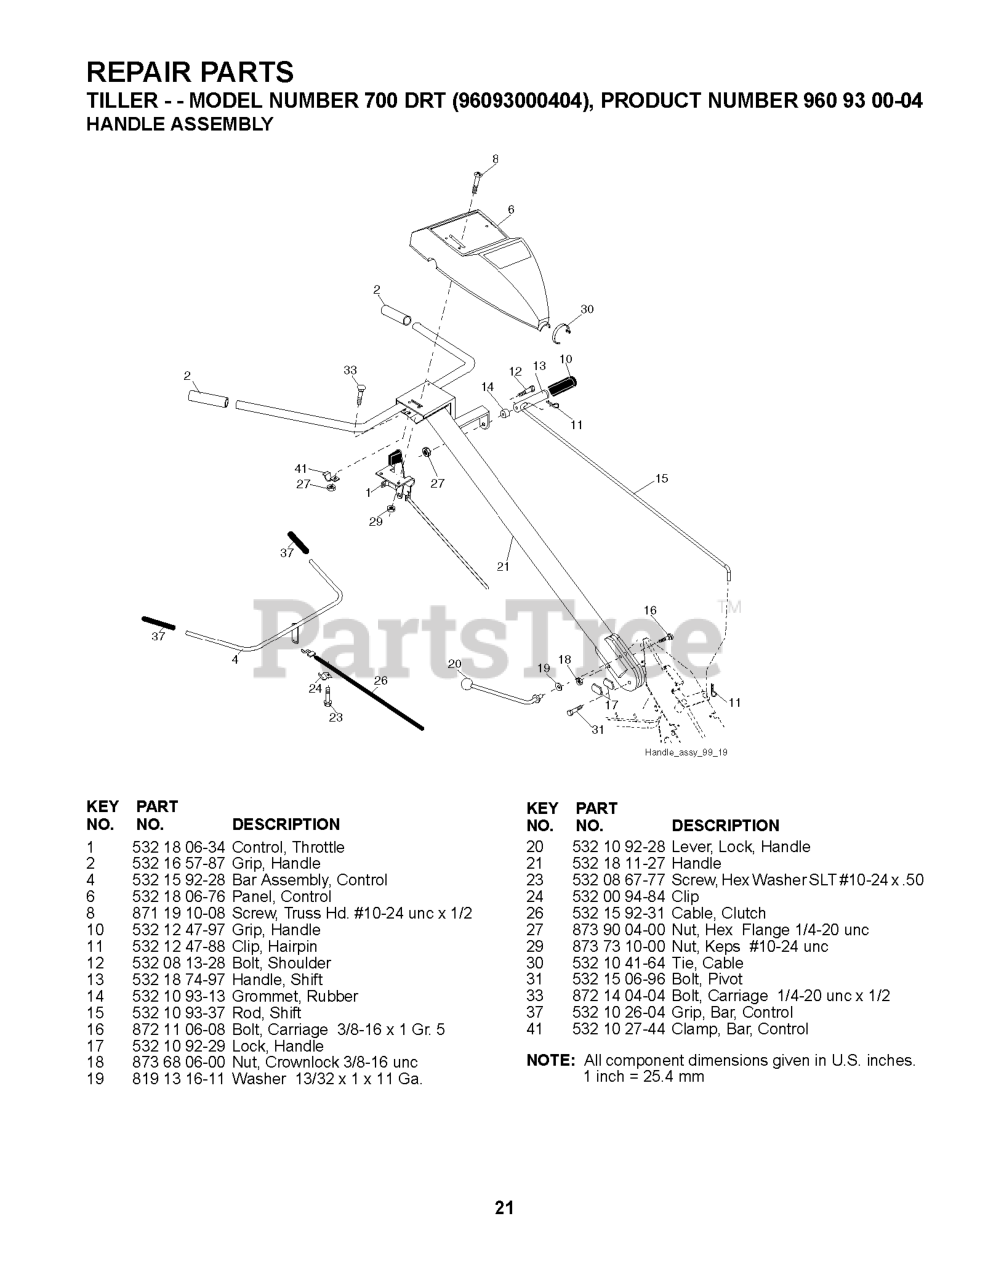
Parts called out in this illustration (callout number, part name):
1	THROTTLE.CONTROL.CRT.TILLER
2	GRIP.HANDLE.BLACK
4	CONTROL BAR ASSY
6	RP CONTROL PANEL
8	SCREW.PNHD.10-24
10	GRIP T
11	RETAINER M
12	SHOULDER BOLT ST
13	HANDLE.SHIFT.TILLER
14	GROMMET.RUBBER.CRT.TILLER
15	SHIFT ROD CRT
16	BOLT D
17	LOCK.HANDLE.CRT
19	WASHER CRT
20	LEVER.LOCK.CRT
21	REPL BY 532 1805-17
23	TAPPING SCREW
24	CONDUIT.CLIP.PLATED
26	CABLE.CLUTCH
27	NUT T
29	NUT **
30	TIE CABLE CRT
31	BOLT.PIVOT
33	BOLT
37	GRIP BAR CRT(1)
41	CLAMP.BAR.CRT.BLACK
